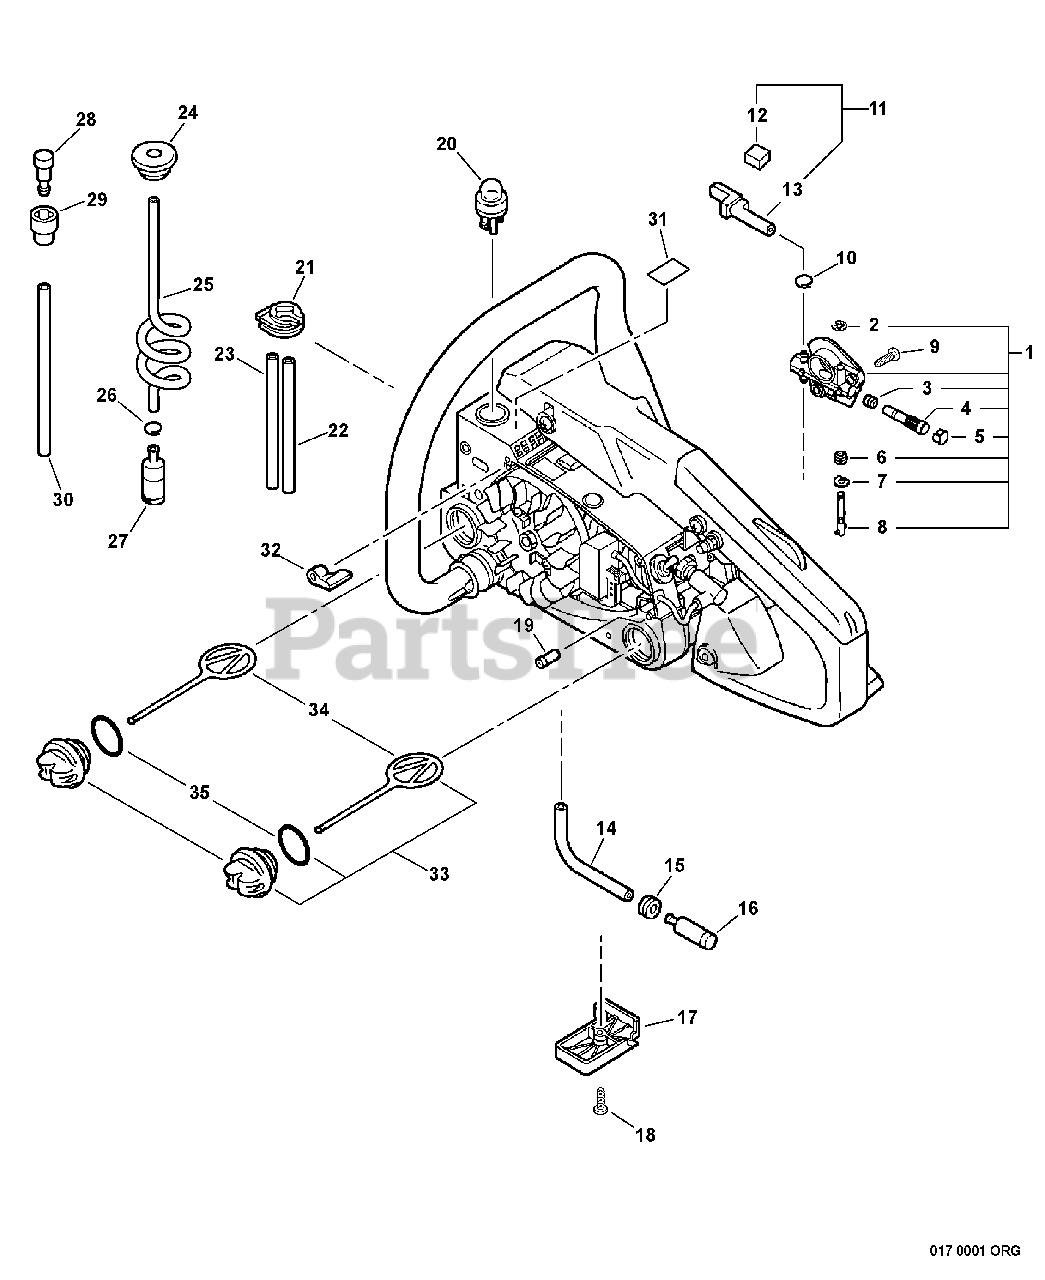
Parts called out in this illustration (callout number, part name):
1	AUTO-OILER ASSY
4	PLUNGER ASSY
5	CAP, PLUNGER
8	ADJUSTER, OILER
9	SCREW 5×12
10	CLIP Ø6.5 MM
11	PIPE KIT, OIL
12	PAD, FOAM
13	PIPE, OIL OUTLET
14	PIPE 3×6×115 BLACK
15	GROMMET
16	FILTER, OIL
17	COVER, BOTTOM
18	SCREW 4×16
19	VENT ASSY
20	BULB, PURGE
21	BRACKET, BULB
22	PIPE, FUEL 3x-5x-70 BLACK
23	PIPE, FUEL 2×4×42 CLEAR
24	GROMMET, FUEL
25	PIPE, FUEL 3×6×160
26	CLIP Ø6.5 MM
27	FILTER, FUEL
28	VENT ASSY
29	HOLDER, VENT
30	PIPE, FUEL 3×5×150 BLACK
31	LABEL, PURGE PUMP
33	CAP ASSY, OIL - BLACK
34	CONNECTOR, CAP L= 60 MM
35	O-RING 25
